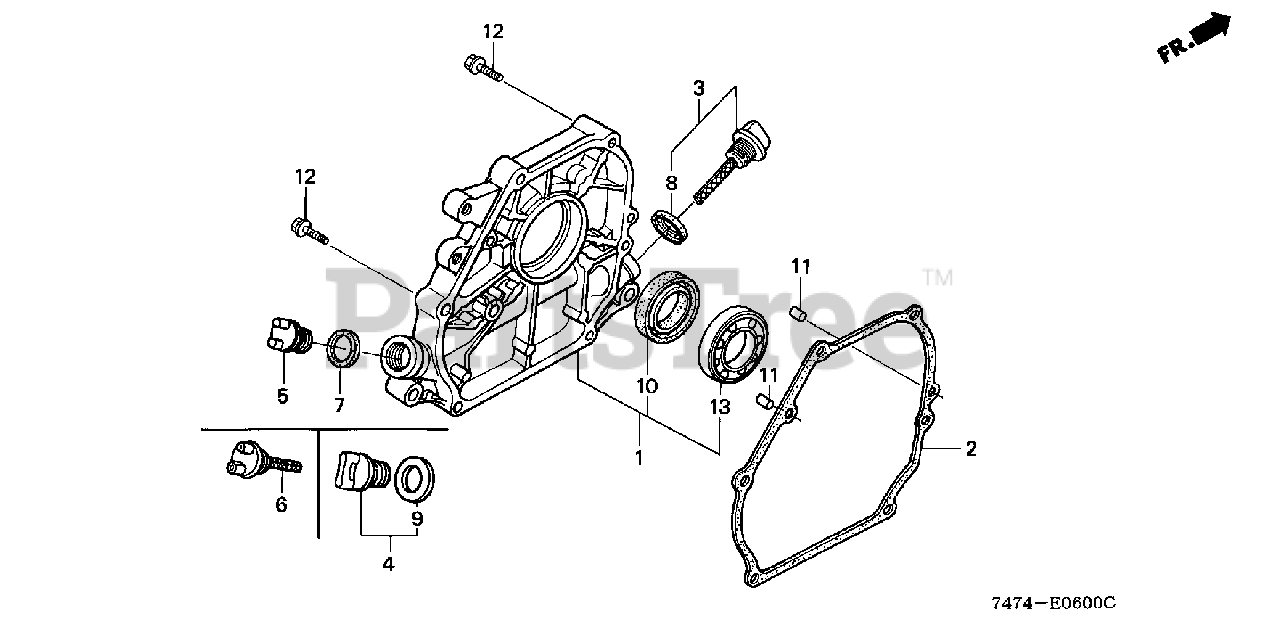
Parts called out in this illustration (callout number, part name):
1	COVER ASSY., CRANKCASE (S-TYPE)
2	GASKET, CASE COVER (NON-ASBESTOS)
3	CAP ASSY., OIL FILLER
6	CAP, OIL HOLE
7	GASKET, OIL FILLER CAP
8	GASKET, OIL FILLER CAP
10	OIL SEAL (25X41X6)
11	PIN A, DOWEL (8X14)
12	BOLT, FLANGE (8X32)
13	BEARING, RADIAL BALL (6205)
